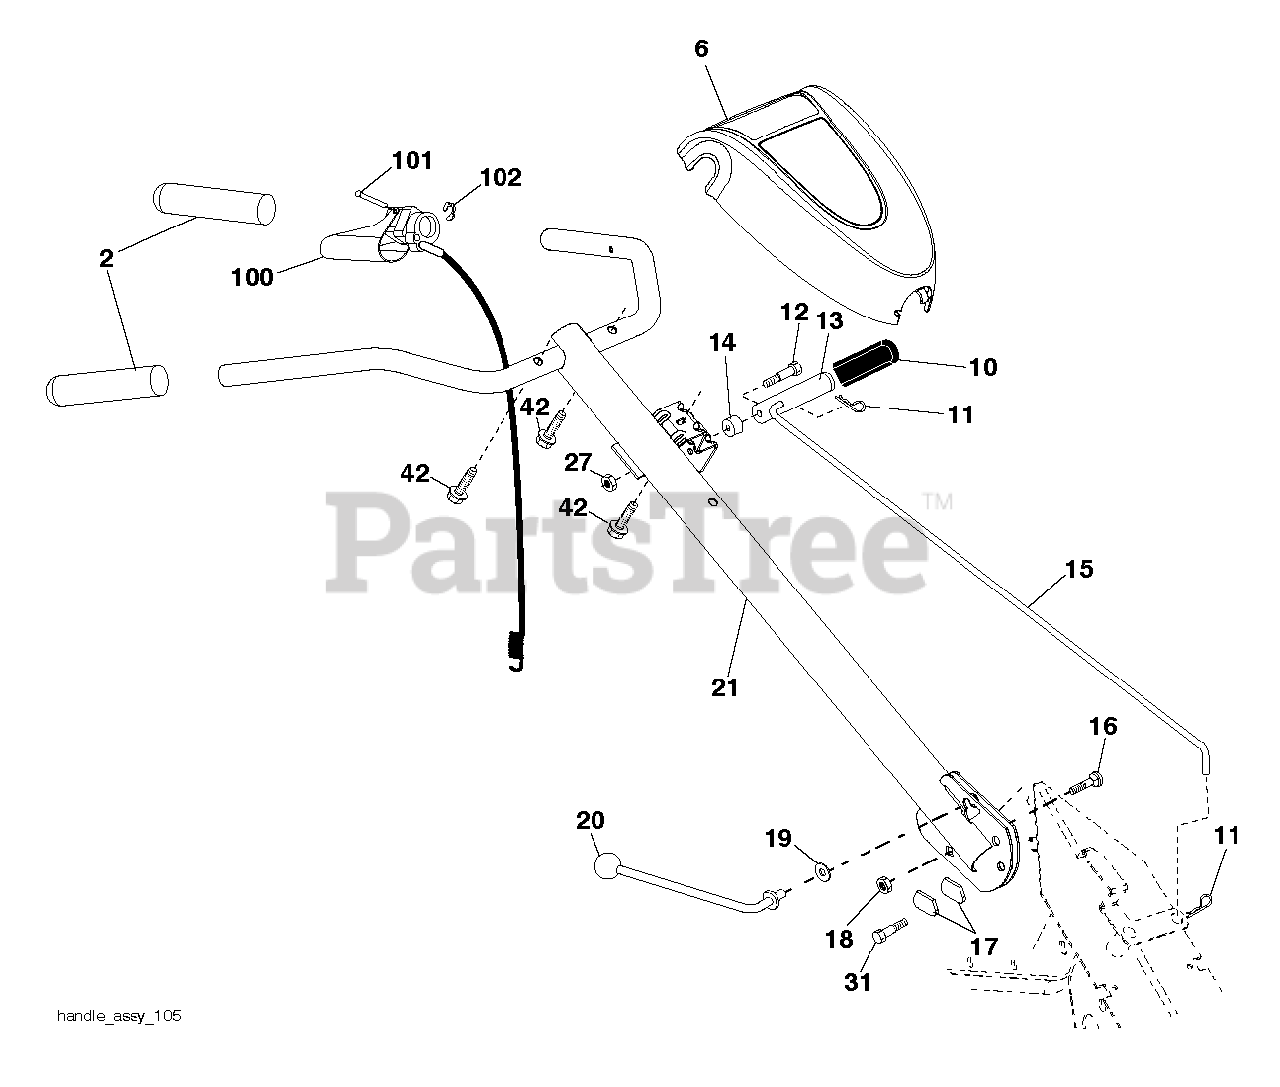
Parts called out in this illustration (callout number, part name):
2	GRIP.1X5.06
6	CONSOLE.BLK.RT.WO/THROTT.PPRO
12	SHOULDER BOLT ST
14	GROMMET.RUBBER.CRT.TILLER
15	ROD.SHIFT.YARD PRO.UNIVERSAL.
17	LOCK.HANDLE.CRT
18	LOCKNUT
19	WASHER CRT
20	LEVER.LOCK.CRT
21	HANDLE.ASM.PLOW.CURVED.BLACK
27	NUT T
31	BOLT.PIVOT
42	SCREW.#10 X 0.750.BOS (2 2)
100	CONTROL.ASSEMBLY.TINE.TILLER
101	PIN, PIVOT
102	RETAINING.RING.#5103-25
